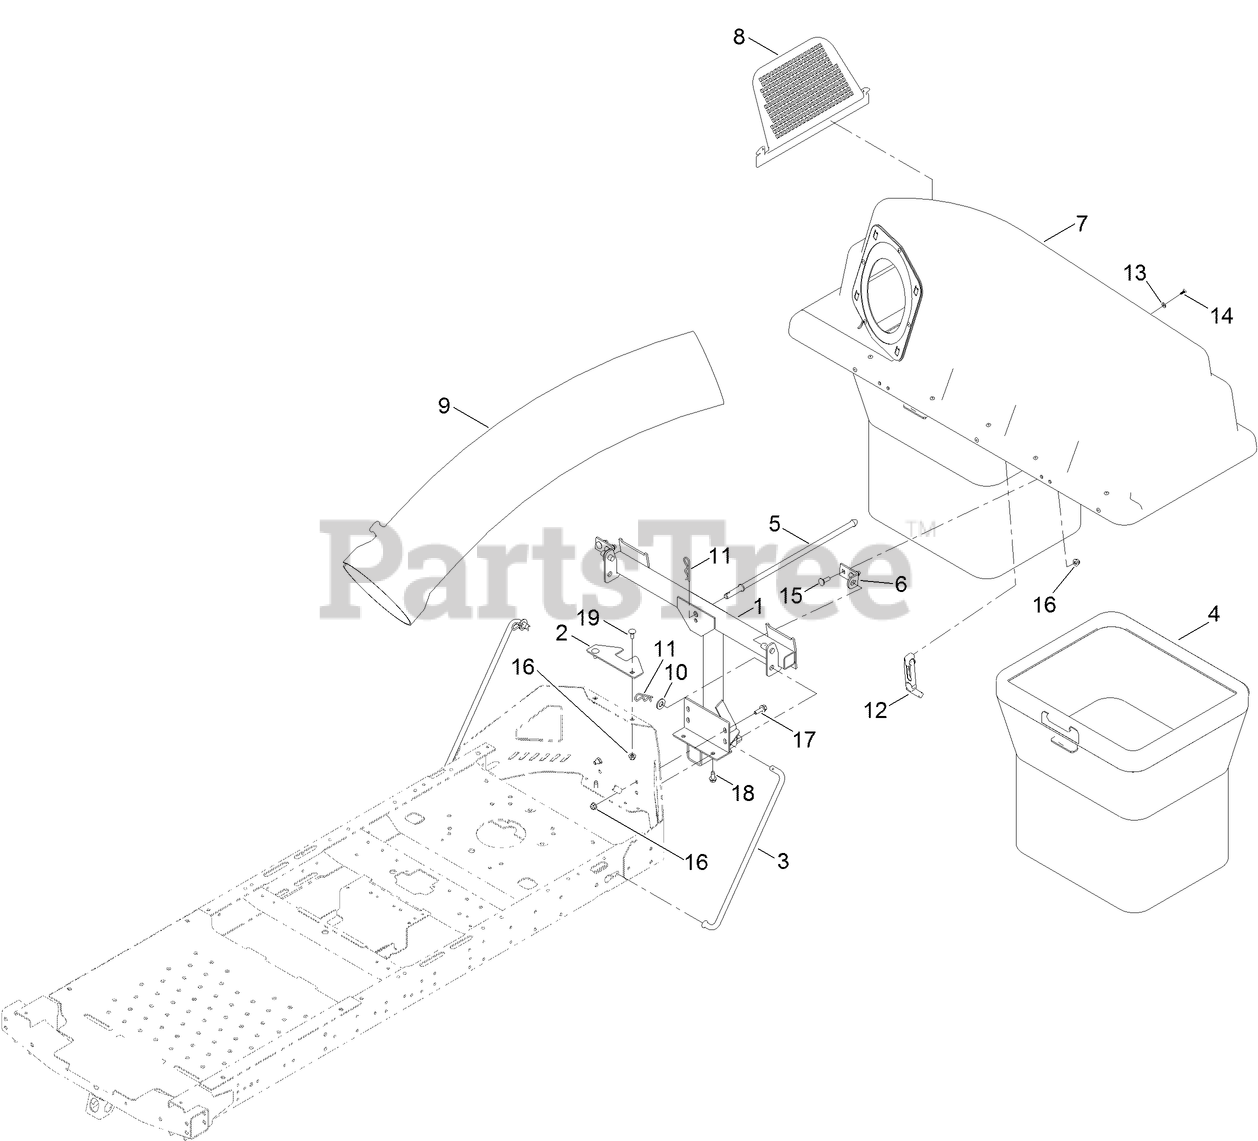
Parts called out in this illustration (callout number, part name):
1	FRAME-PIVOT
2	BRACKET-STABILIZER
3	ROD-SUPPORT, CZ
4	BAG ASM
5	ROD-HOOD, DOWN (HOLD)
6	BRACKET-HOPPER PIVOT
7	TOP ASM-BAGGER
8	SCREEN-BAGGER
9	TUBE-BAGGER
10	WASHER-FLAT
11	PIN-HAIR
12	LATCH-RUBBER
13	WASHER-FLAT
14	SCREW-PLASTIC, PTH
15	BOLT-CARR
16	NUT-HF
17	SCREW-HHF
18	SCREW-HWHTF
19	BOLT-CARR
